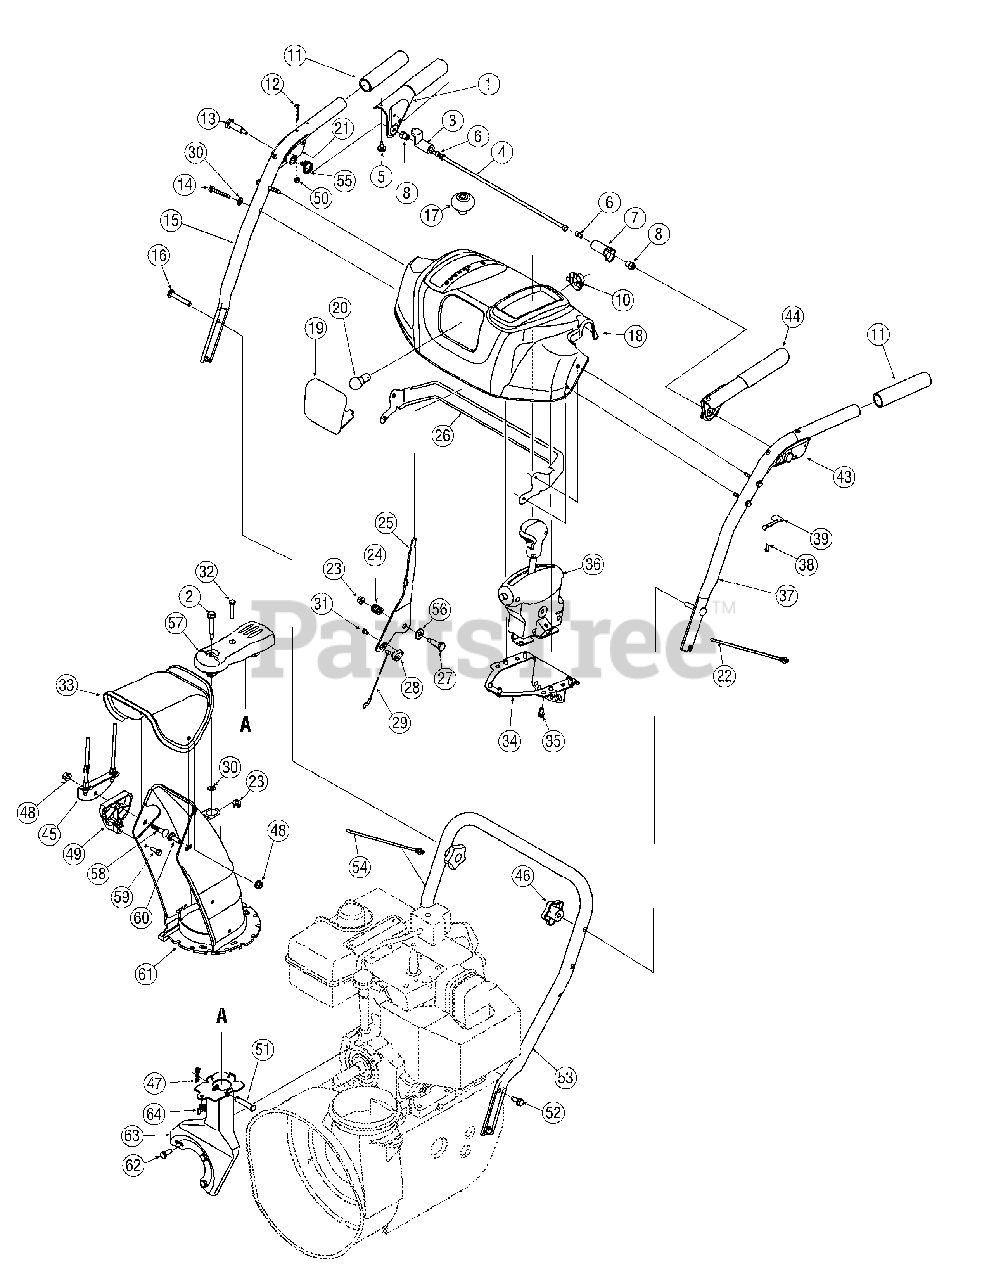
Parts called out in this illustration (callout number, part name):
1	Handle Engagement Assembly RH
2	Flange Shoulder Screw
3	Lock Plate
4	Pivot Rod
5	Rubber Bumper
6	Screw, 1/4-20 x.375
7	Clutch Lock Cam
8	Shoulder Nut, 1/4-20
9	Wire Harness
10	Light Socket
11	Handle Grip
12	Screw, #10-24 x 0.375
13	Shoulder Screw, 1/4-20 x 1.345
14	Screw, 1/4-20 x 1.750
16	Carriage Screw, 5/16-18 x 2.25
17	Shift Knob
18	Handle Panel, K/L-Style, Black
21	Handle Clutch Lock - RH
22	Cable Tie
23	Flange Lock Nut, 1/4-20
24	Compression Spring
25	Shift Lever
26	Panel Bracket
27	Shoulder Screw
28	Cable Barrel Holder
29	Speed Selector Cable
30	Flat Washer, .25 x .630 x .0515
31	Screw, #10-16 x .500
32	Hex Screw, 1/4-20 x 1.50
33	Upper Chute
34	Joystick Bracket
35	Hi-Lo Screw, 1/4-15 x 0.5
36	4 Way Chute Control Assembly Service Kit
38	Screw, #8-16 x 0.50
39	Clutch Lock Spring
40	Steering Control
41	Pin, 3/16
42	E Ring
43	Handle Clutch Lock - LH
44	Handle Engagement Assembly LH
46	Handle Knob Assembly
47	Bow Tie Cotter Pin
48	Flange Lock Nut, 5/16-18
49	Chute Tilt Cable Guide
50	Hex Lock Nut, #10-24
51	Clevis Pin
52	AB Screw, 5/16-18 x 0.75
54	Cable Tie
55	Torsion Spring
56	Flat Washer
57	Joystick Pulley Cover
58	Carriage Bolt, 5/16-18 x 1.50
59	Hi-Lo Screw, 1/4-15 x .75
60	Carriage Bolt, 5/16-18 x 1.0
61	Lower Chute
62	Hex Screw, 5/16-24 x .750
63	Support Bracket
64	Wing Nut, 1/4-20
